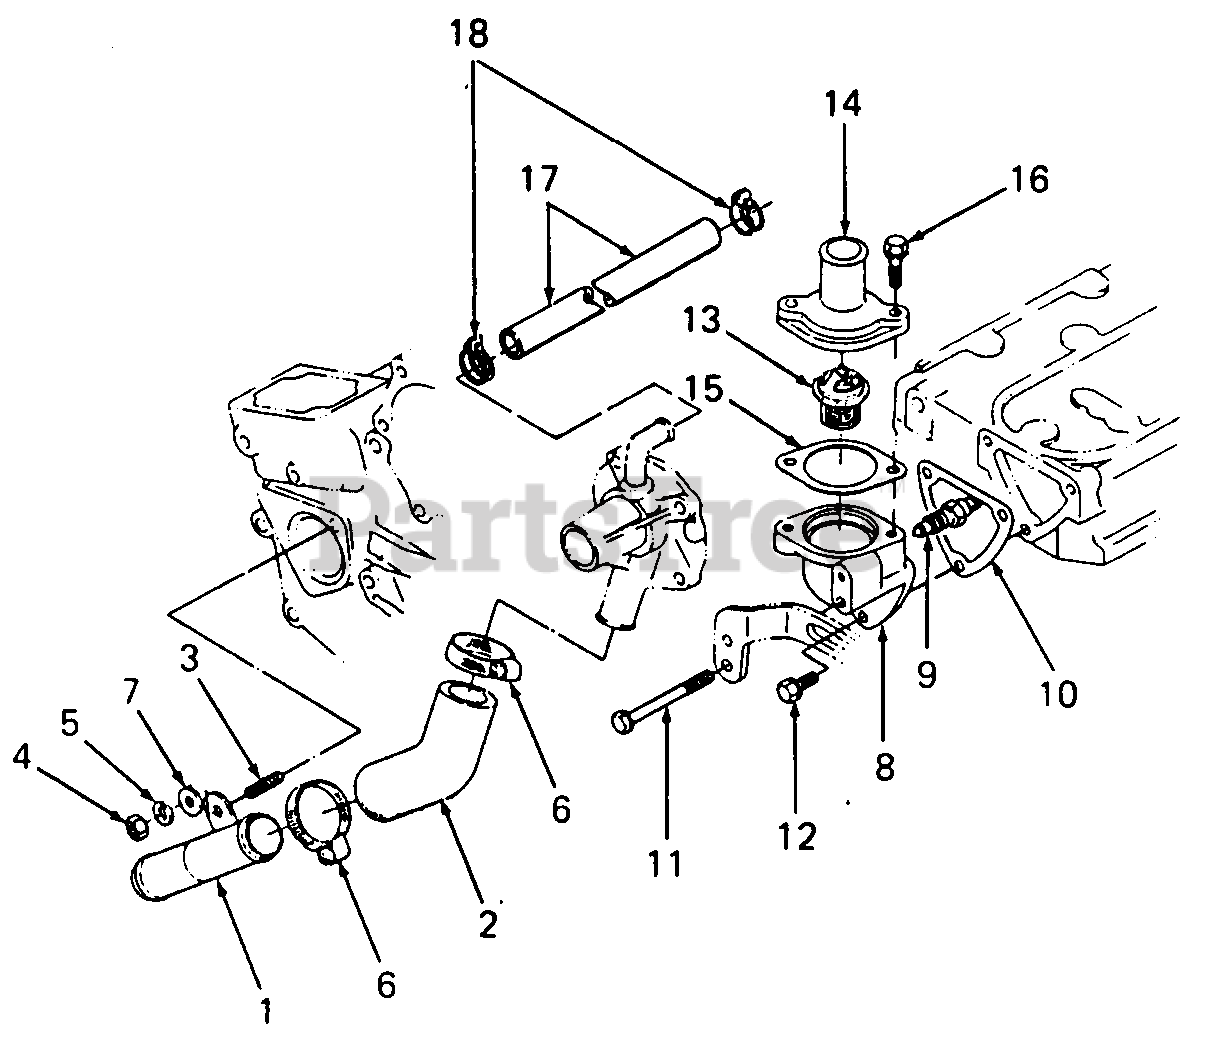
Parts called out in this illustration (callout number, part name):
5	Washer, Spring
7	Washer, Plain
8	Flange, Water
9	Thermoswitch Assy
10	Gasket, Water Flange
13	Thermostat Assy
14	Cover, Thermostat
15	Gasket
17	Pipe, Water Return
